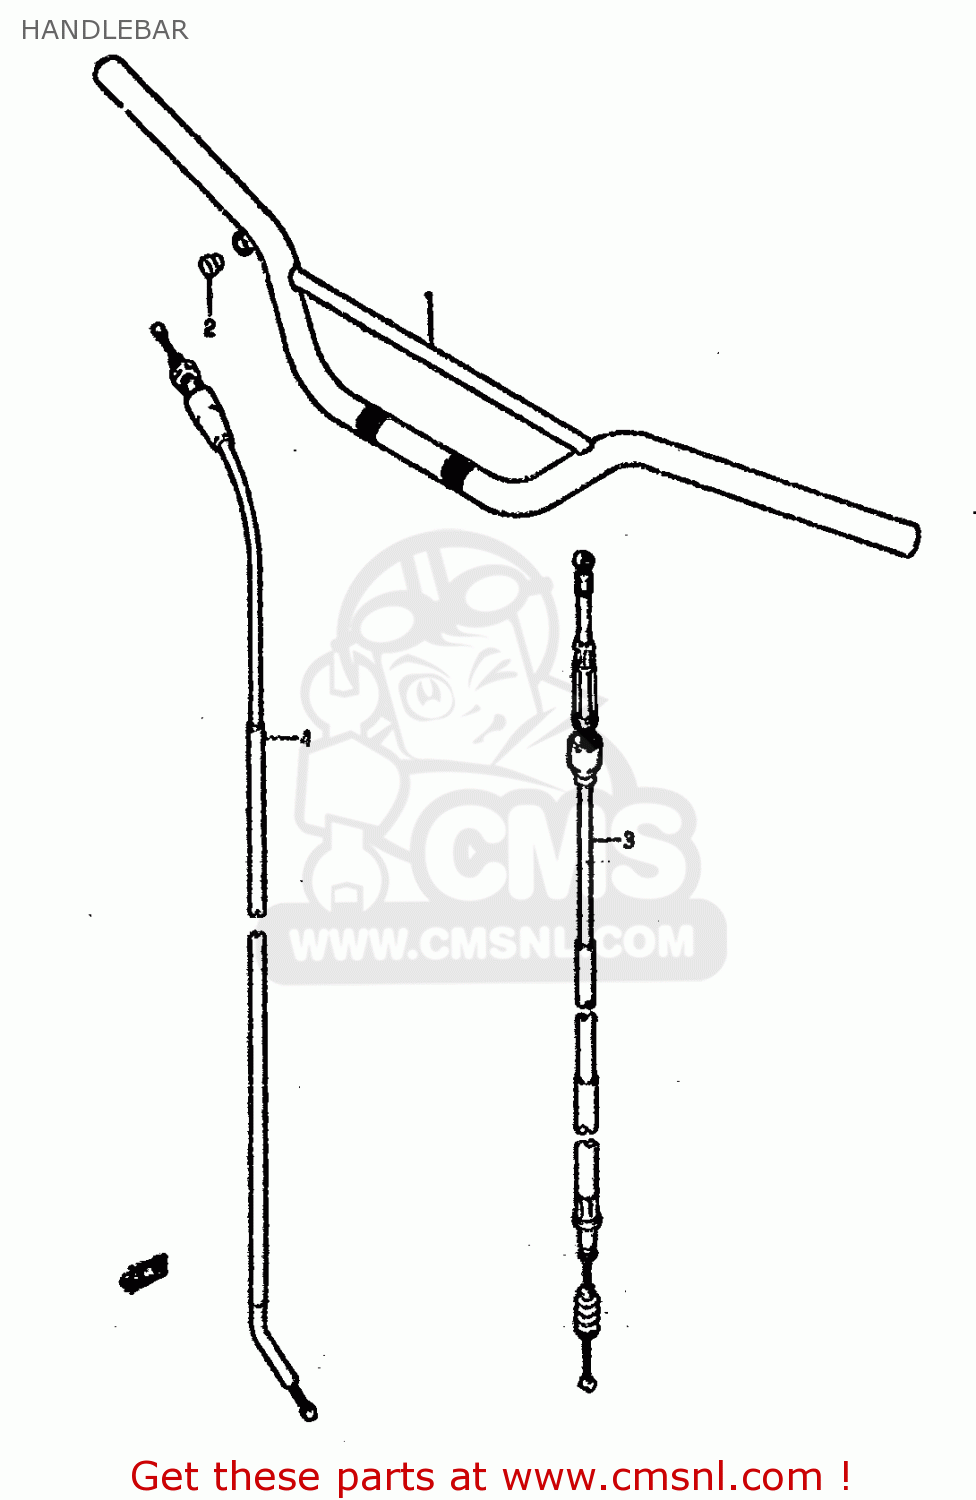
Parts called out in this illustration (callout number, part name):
1	HANDLEBAR
2	CAP(OD:14)
3	CABLE ASSY,CLUTCH
4	CABLE ASSY,THROTTLE
